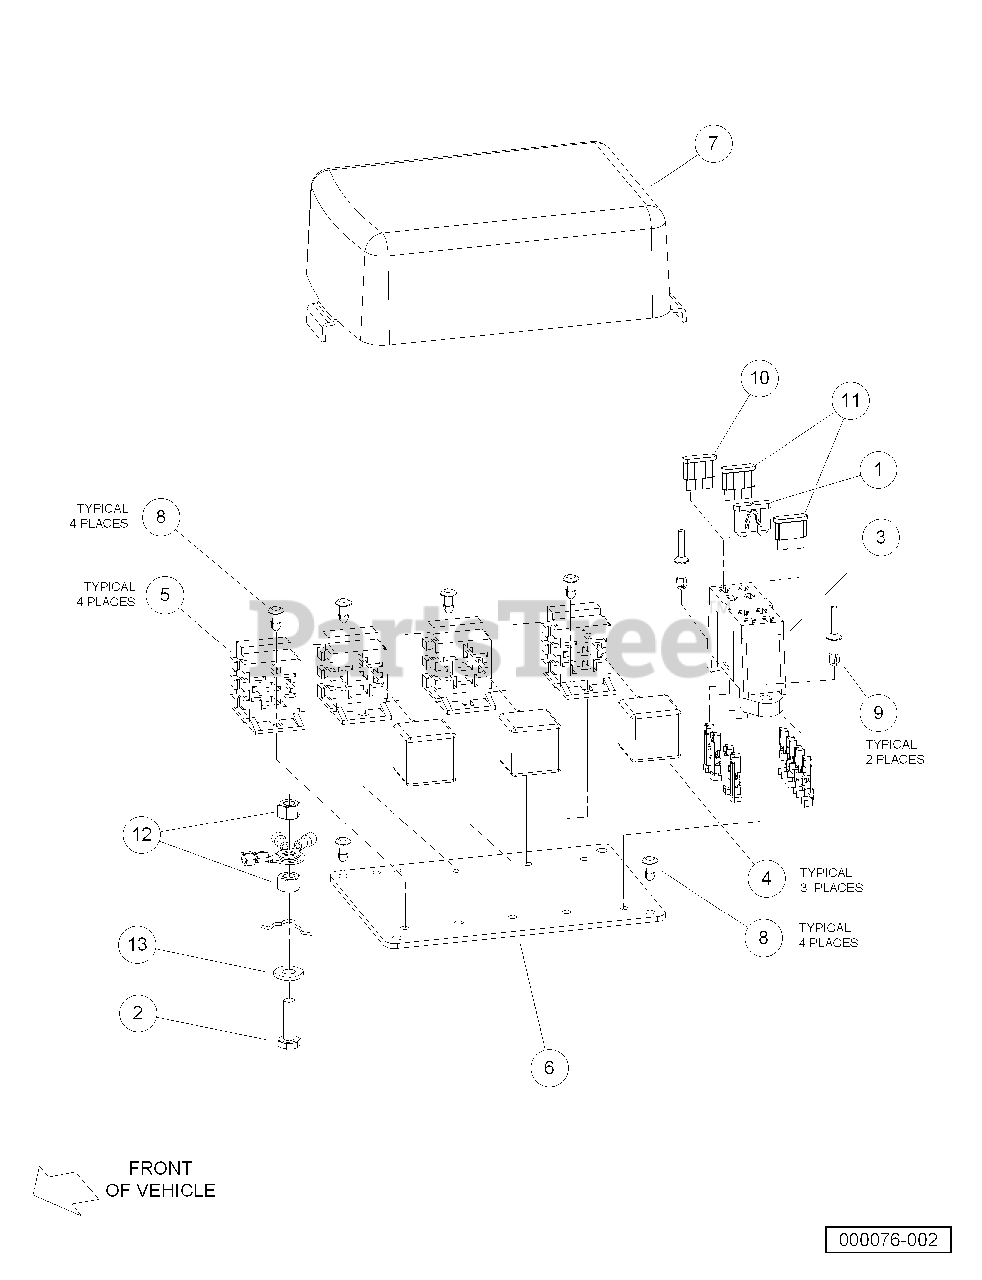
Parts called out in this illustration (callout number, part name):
1	Fuse, 10-Amp
2	Screw, 1/4-20 X .88 Hex Hd Cap
3	Fuse Block
4	Relay, Mini ISO, SPDT
5	Connector, Relay
6	Plate, Electrical
7	Cover, Electrical
8	Fastener, Push-in
9	Rivet, Drive
10	Fuse, 25-Amp
11	Fuse, 30-Amp
12	Locknut, 1/4-20 Dimpled
13	Washer, 1/4 Type A Narrow Flat
